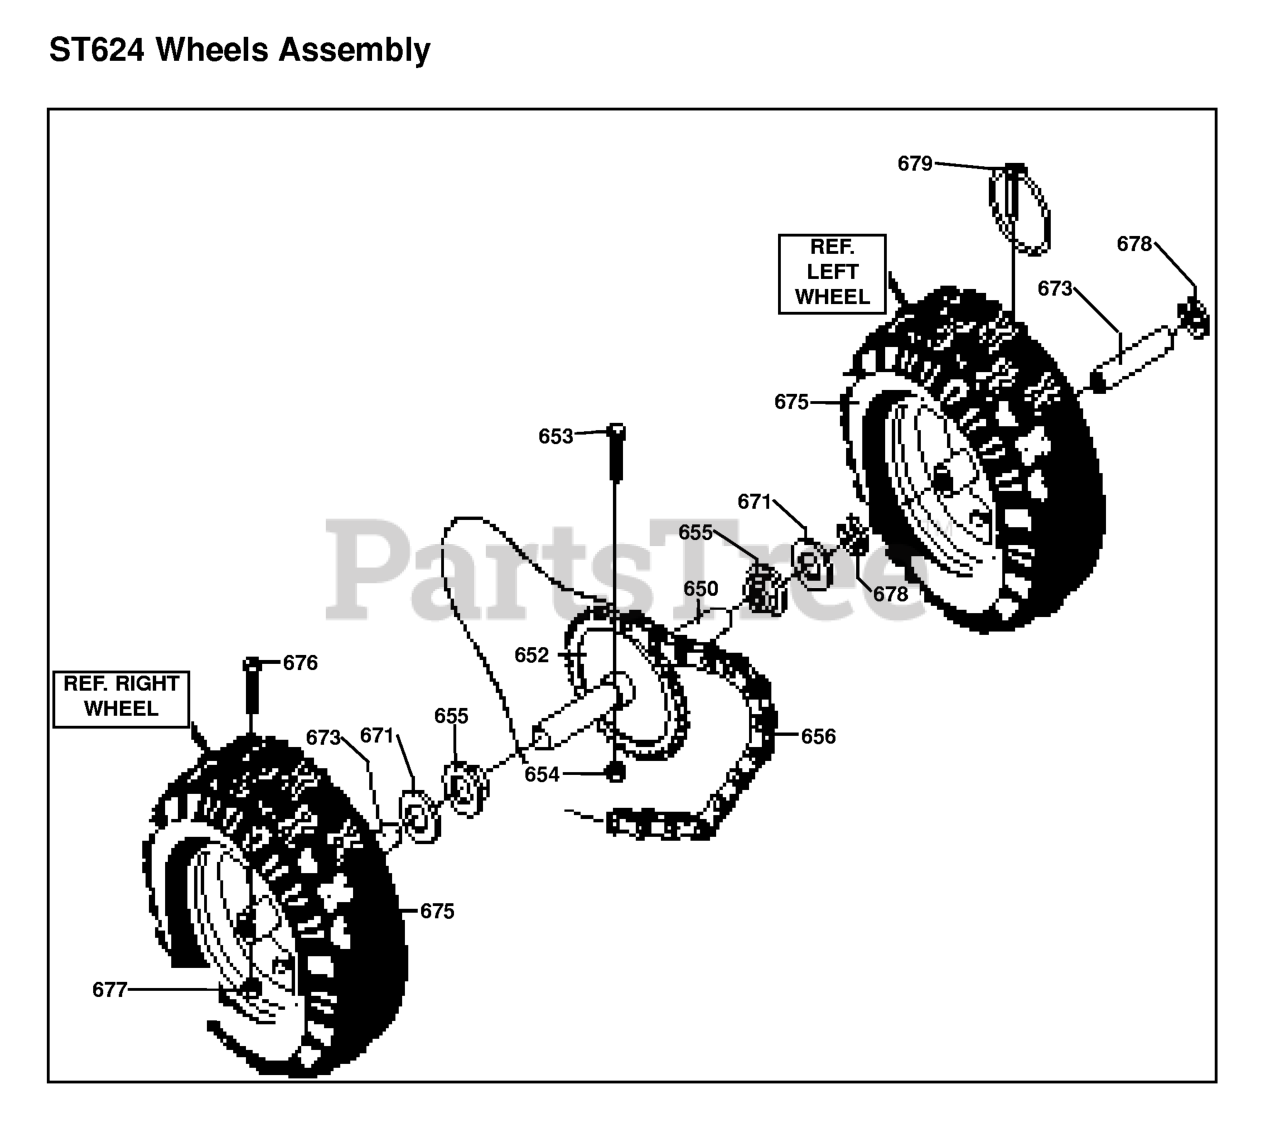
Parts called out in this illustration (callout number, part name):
650	AXLE SHAFT
652	HUB SPROCKET
655	FLANGE BEARING
673	BUSHING, WHEEL 4" LG
675	TIRE & RIM 13X5.0X6
678	RETAINER RING
